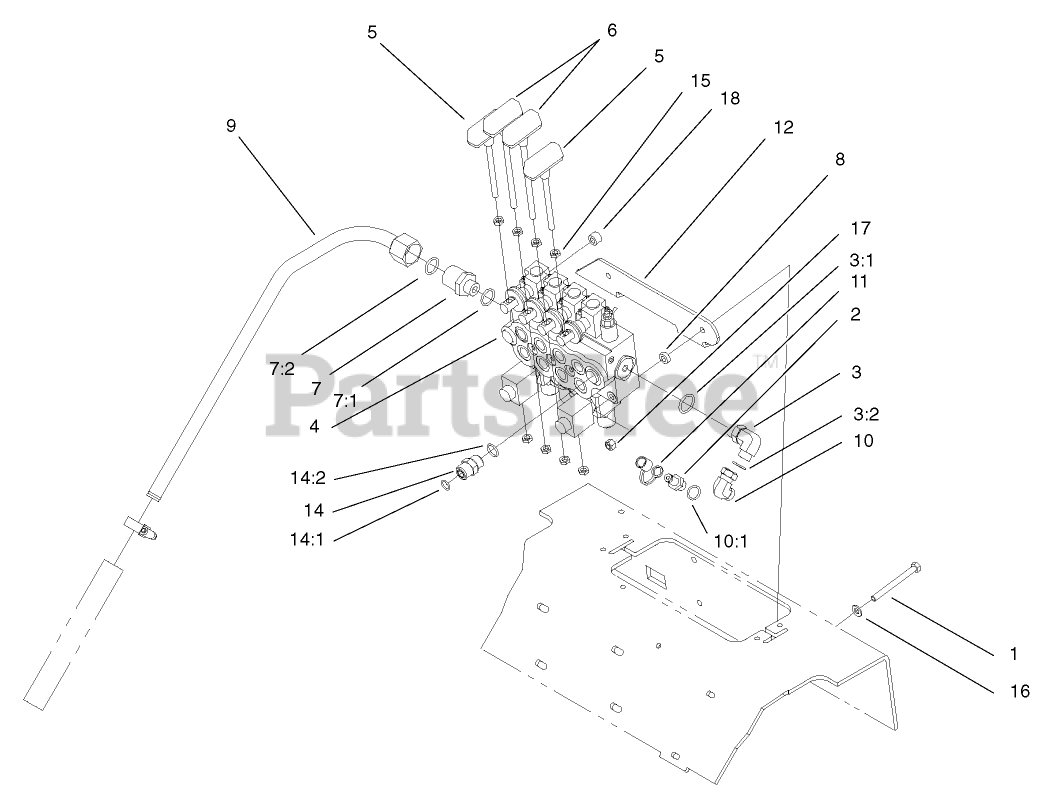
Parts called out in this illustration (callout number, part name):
1	SCREW-HH
2	NIPPLE-TEST
3	FITTING-HYD, 90 DEG
3:1	O-RING
3:2	O-RING
4	VALVE-HYDRAULIC, 4-SPOOL
5	CYLINDER HANDLE ASM
6	DRIVE HANDLE ASM
7	FITTING-STR
7:1	O-RING
7:2	O-RING
8	SPACER
9	HYD TUBE ASM
10	FITTING-HYD, 90 DEG
10:1	O-RING
11	CAP-DUST
12	BRACKET-COVER, MOUNT
14	FITTING-STRAIGHT
14:1	O-RING
14:2	O-RING
15	NUT-HEX
16	WASHER-PLAIN
17	NUT-LOCK, NI
18	SPACER
